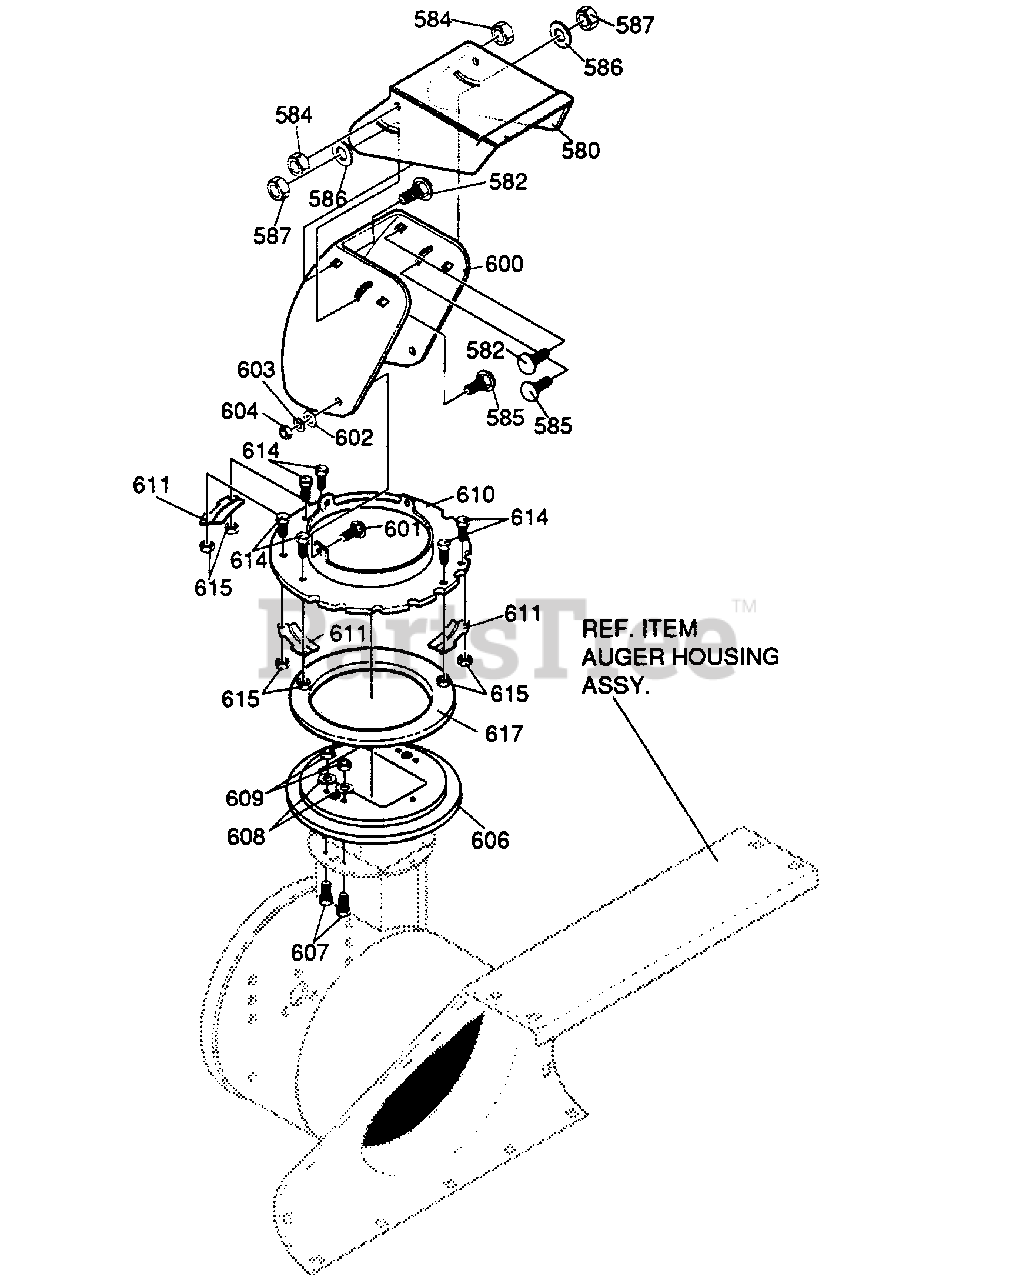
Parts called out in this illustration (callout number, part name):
580	UPPER CHUTE
582	SCREW, 5/16-18x.75 SLTRMA
584	NUT, 5/16-18 HEXNYL
585	SCREW, 5/16-18x.75 SLTRMA
586	PLASTIC WASHER, .315x.75x.064
587	NUT, 5/16-18 HEXNYL
600	CHUTE, LOWER
601	CARR. BOLT, 5/16-18x.75
602	FLATWASHER, .344x.69x.065
603	WASHER, HVSPTLK
604	NUT, 5/16-18 REGHEX
606	COLLAR, CHUTE ADAPT
607	SCREW, 1/4-20 X .75 IN.
608	FLATWASHER, .281 X.63X.065
609	NUT 1/4-20 REGHEXCTRLK
610	FLANGE CHUTE
611	CLIP, CHUTE RET.
614	SCREW #8-32X.63 WAHHMA
615	NUT, #8-32 HEXCTRLK
617	RING, FLANGED
